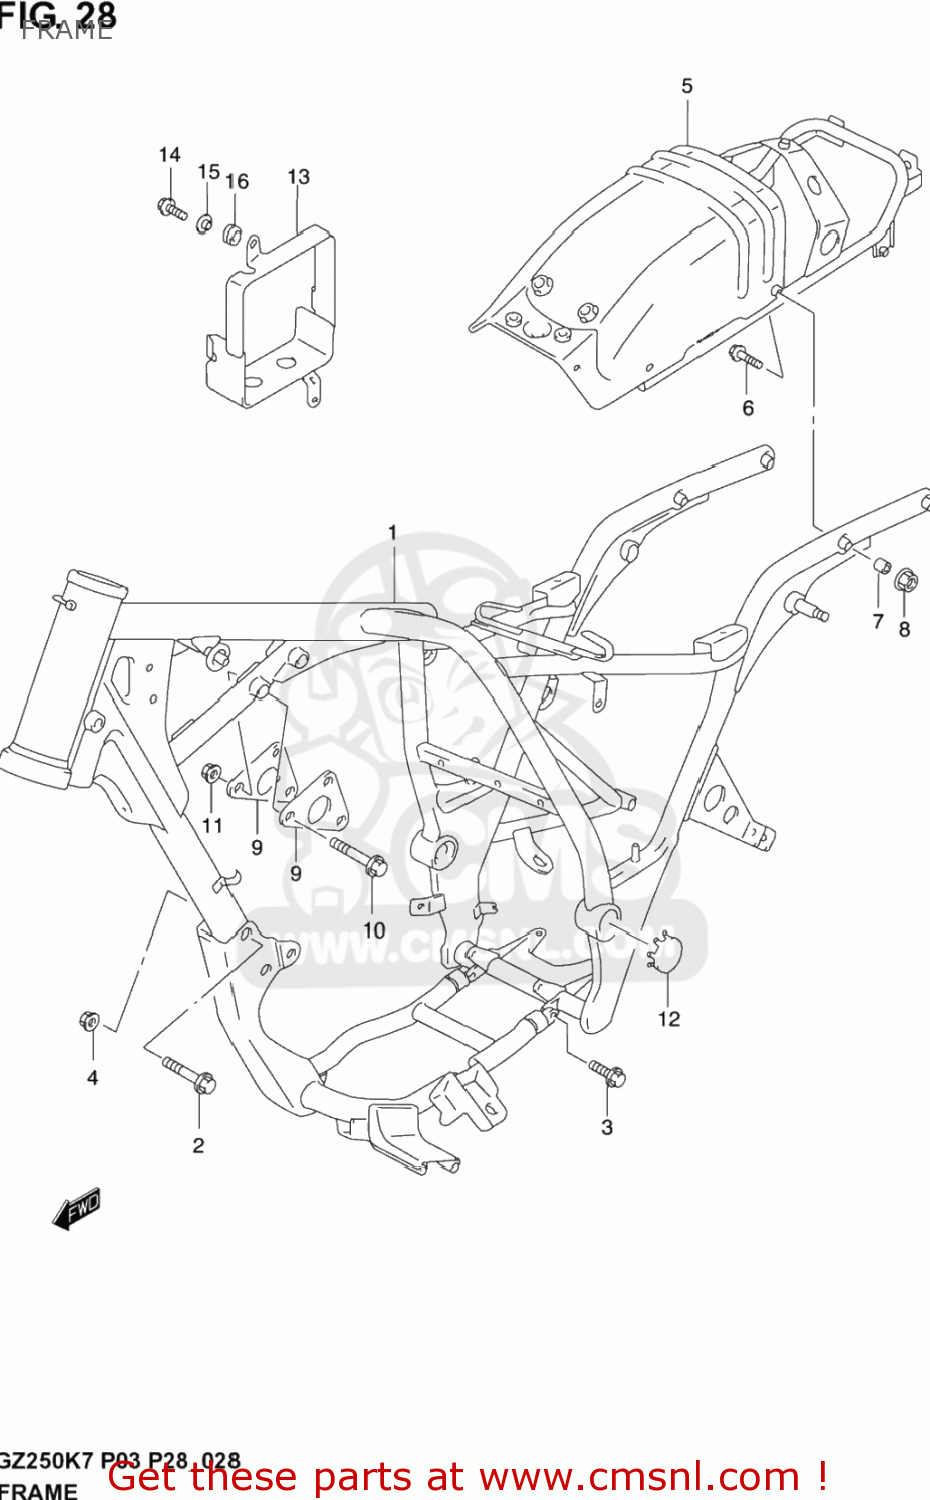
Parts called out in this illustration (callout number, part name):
1	FRAME (BLACK)
2	BOLT
3	BOLT
4	NUT
5	BRACE,REAR FR.
6	BOLT
7	SPACER(8.5X16X10)
8	NUT
9	PLATE ENGINE M
10	BOLT(8X50)
11	NUT
12	CAP,RR SWINGING ARM PIVOT,R
13	HOLDER COMP. B
14	BOLT
15	WASHER
16	CUSHION
